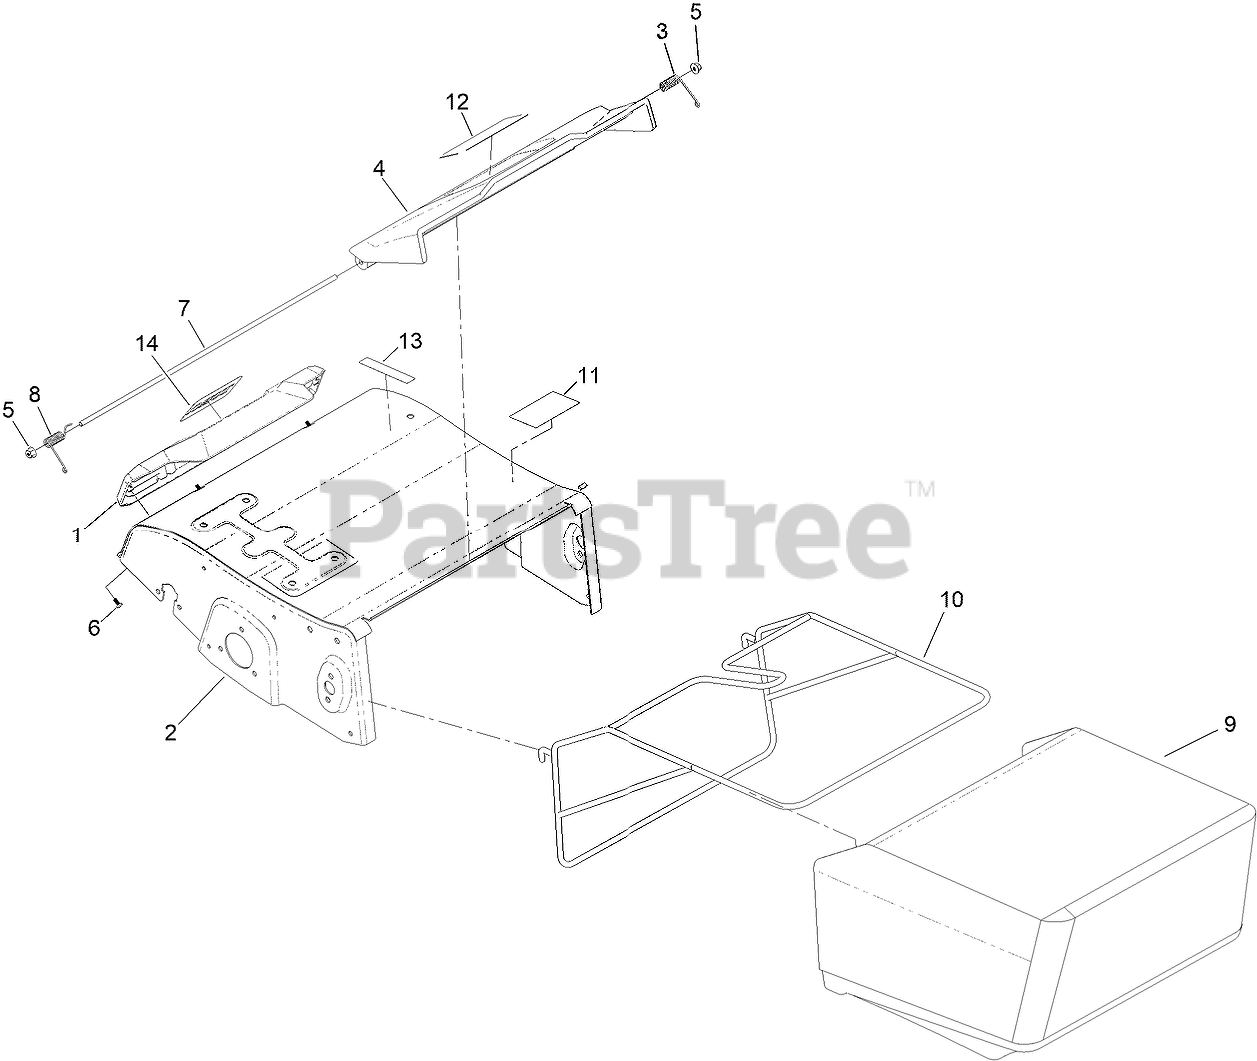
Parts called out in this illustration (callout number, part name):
1	FRONT COWLING
2	DECK-STEEL
3	SPRING-FLAP, REAR RHS
4	FLAP-REAR
5	NUT-LOCK, FLANGE
6	SCREW-PAN HEAD
7	ROD-FLAP
8	SPRING-FLAP, REAR LHS
9	GRASS BAG - FABRIC ASSY
10	GRASS BAG STEEL FRAME
11	DECAL - SERIAL NO
12	DECAL - SAFETY
13	DECAL - HOC
14	DECAL - LOGO TORO
